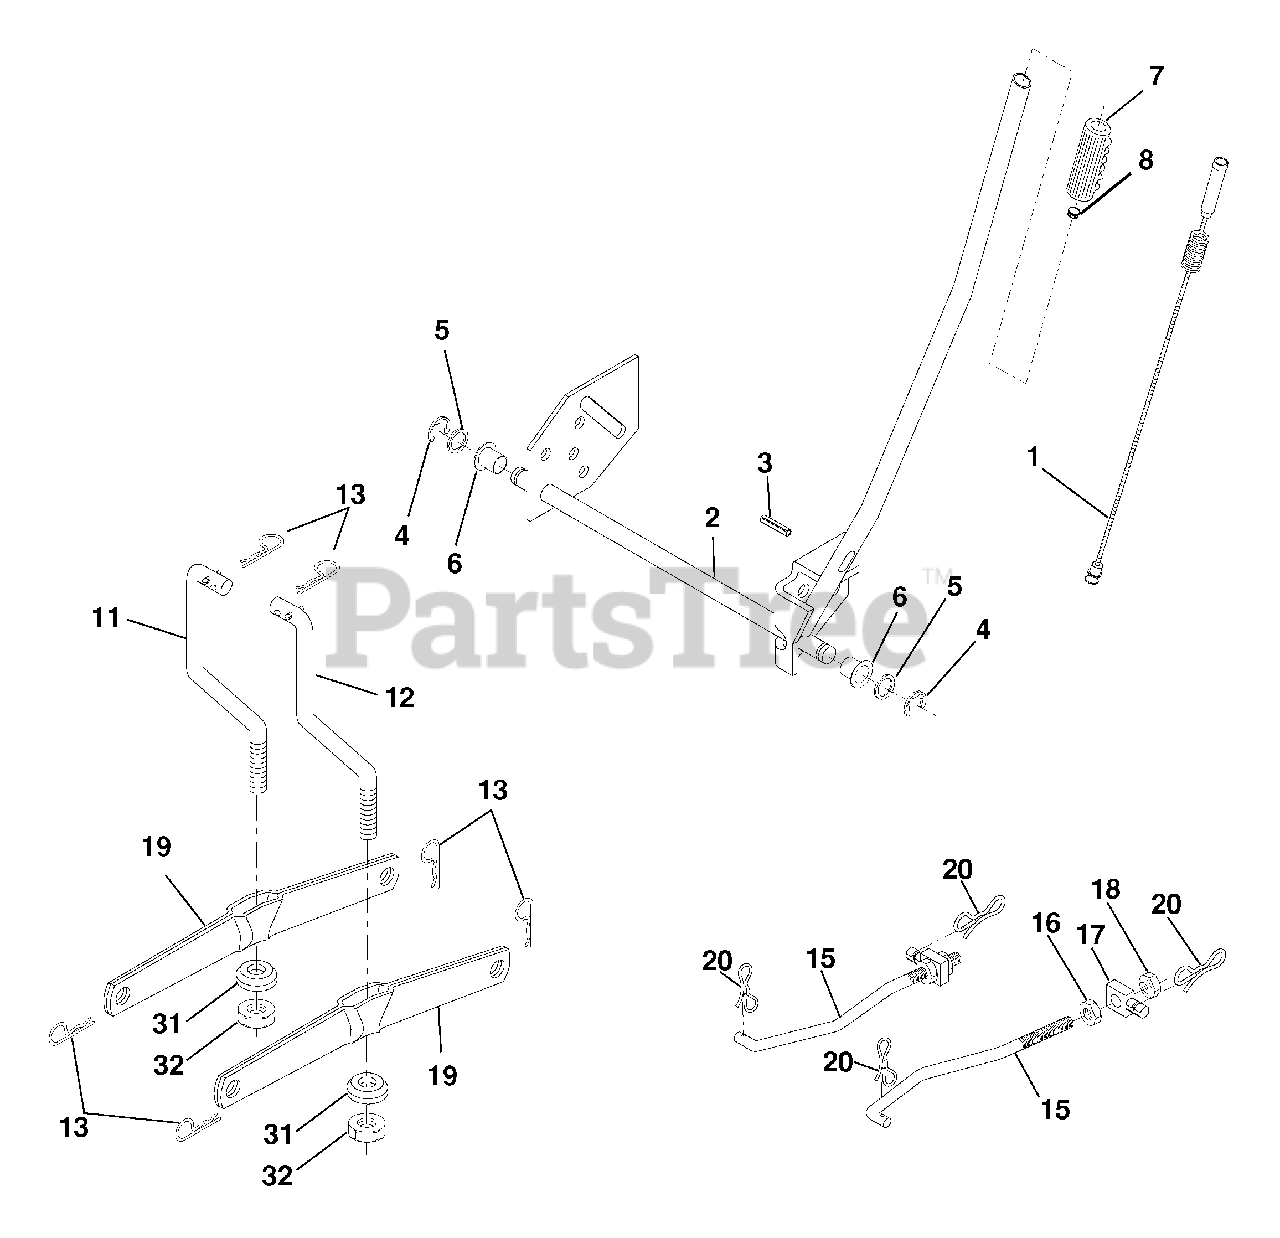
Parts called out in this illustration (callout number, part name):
1	Wire Asm Inner/Sprg w/Plunger
2	Shaft Asm Lift
3	Pin Groove
4	E Ring #5133-62
5	Washer 21/32 x 1 x 21 Ga.
6	Bearing Nylon
7	Grip Handle
8	Button Plunger
11	Link Lift Lh
12	Link Lift Rh
13	Retainer Spring
15	Link Front
16	Nut Jam Hex 1/2-13 unc
17	Trunnion Blk Zinc
18	Nut Lock w/Wsh 1/2-13 unc
19	Arm Suspension Rear
20	Pin Cotter 7/16 Bow Tie Lock
31	Bearing Pvt Lift
32	Nut Crownlock 3/8-24
